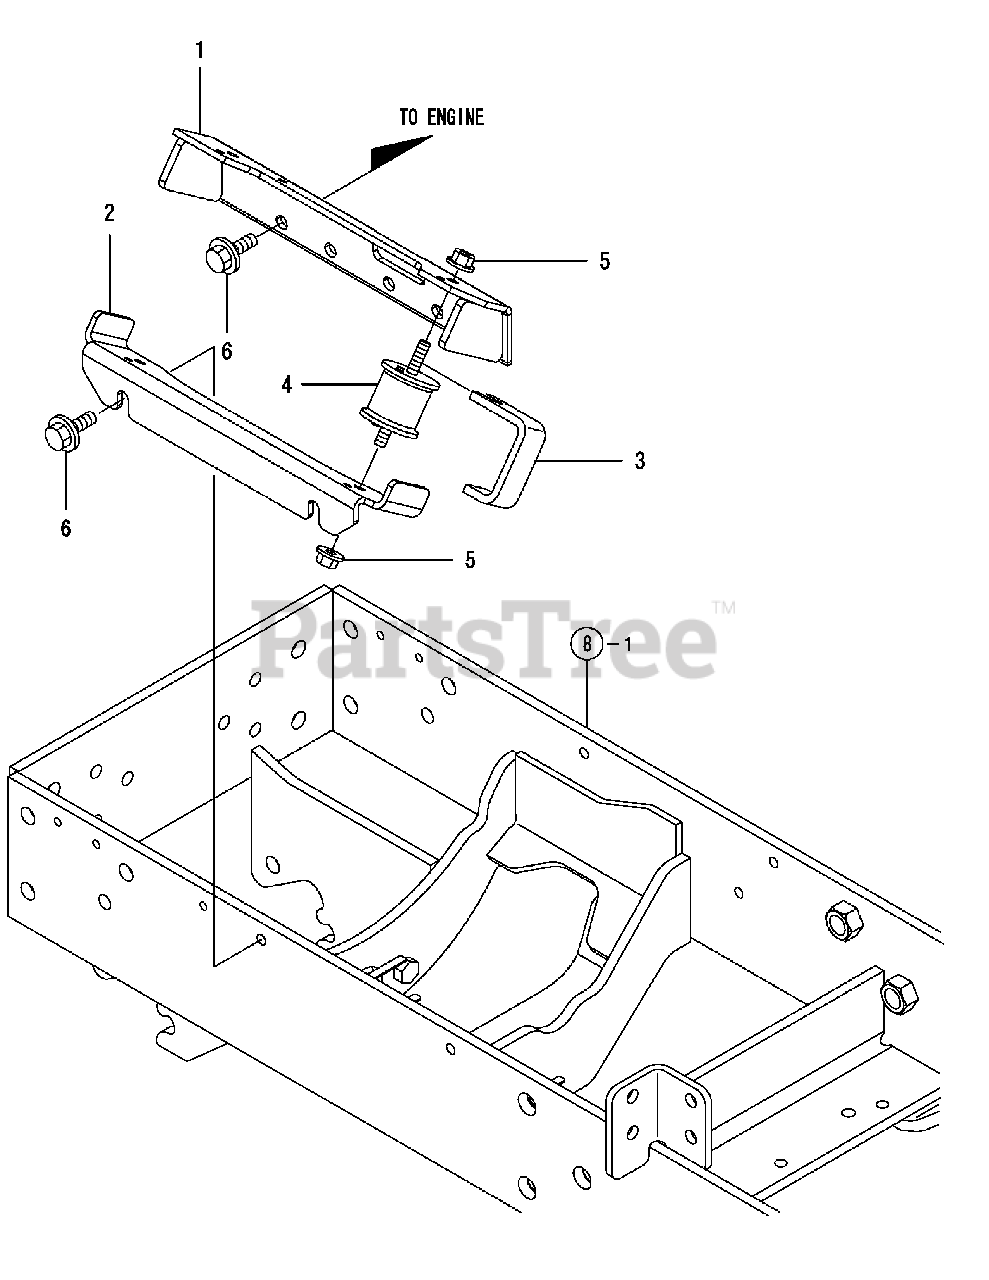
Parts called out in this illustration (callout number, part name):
1	STAY CMP, ENGINE
2	MOUNT STAY, FRAME
5	NUT W/WASHER 8
6	BOLT M10X 20 PLATED
